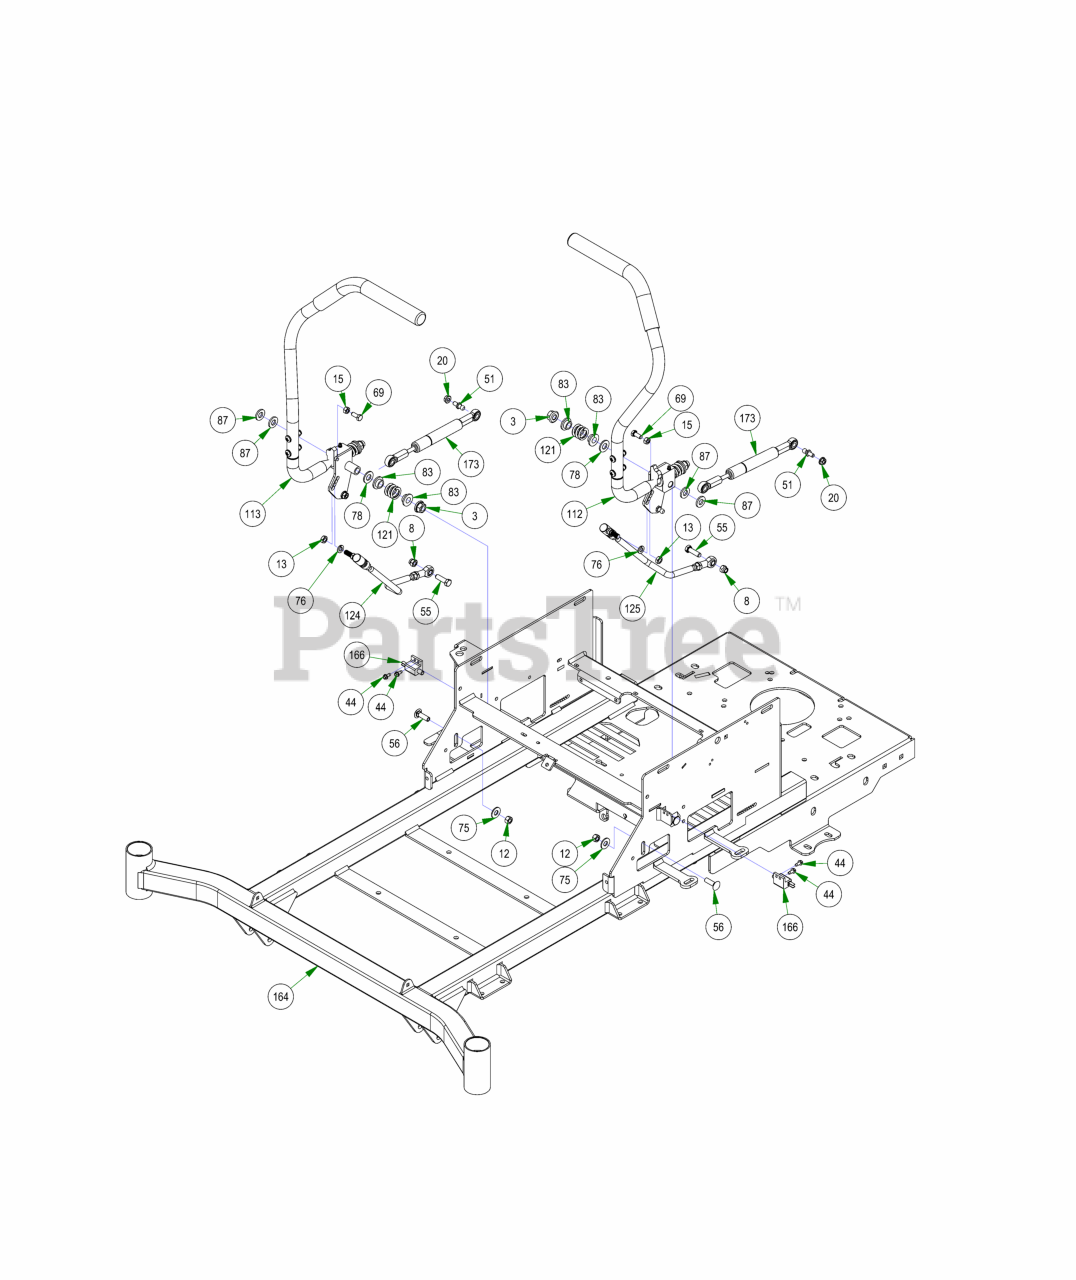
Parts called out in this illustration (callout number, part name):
3	1/2-13 HEX FLANGE AUTO OVAL LOCKNUT (GR.F) ZINC/WAX
8	3/8-16 NYLON INSERT LOCKNUT ZINC
12	3/8-16 HEX NUT ZINC
13	3/8-24 HEX NUT ZINC YELLOW
15	5/16-18 HEX NUT ZINC
20	5/16-18 HEX SERRATED FLANGE NUT HARD/ZINC
44	12-24 X 1/2 HEX WASHER UNLSOT F TCS ZINC
51	10mm Damper Ball Stud-Steering
55	3/8-16 X 1-1/4 HEX CAP SCREW (GR.5) ZINC
56	3/8-16 X 1-1/4 CARRIAGE BOLT ZINC
69	5/16-18 X 3/4 HEX CAP SCREW (GR.5) ZINC
75	3/8 FLAT WASHER USS (1" OD) ZINC
76	3/8 SPLIT LOCKWASHER ZINC
78	1/2 SAE FLAT WASHER (1-1/16" OD) GR.8 ZINC YELLOW
83	.525 ID SHOULDER WASHER NYLON
87	.505 ID X 1.000 OD X .125 THICK FLAT WASHER NYLON
112	ZT Steering Arm Assembly, Left Hand
113	ZT Steering Arm Assembly-Right Hand
121	Drive Lever Spring
124	Push Rod-Right
125	Push Rod-Left
164	2023 MZ-Avenger 54-60 Frame - Painted
166	Safety Switch
173	ZT Avenger Steering Dampener
